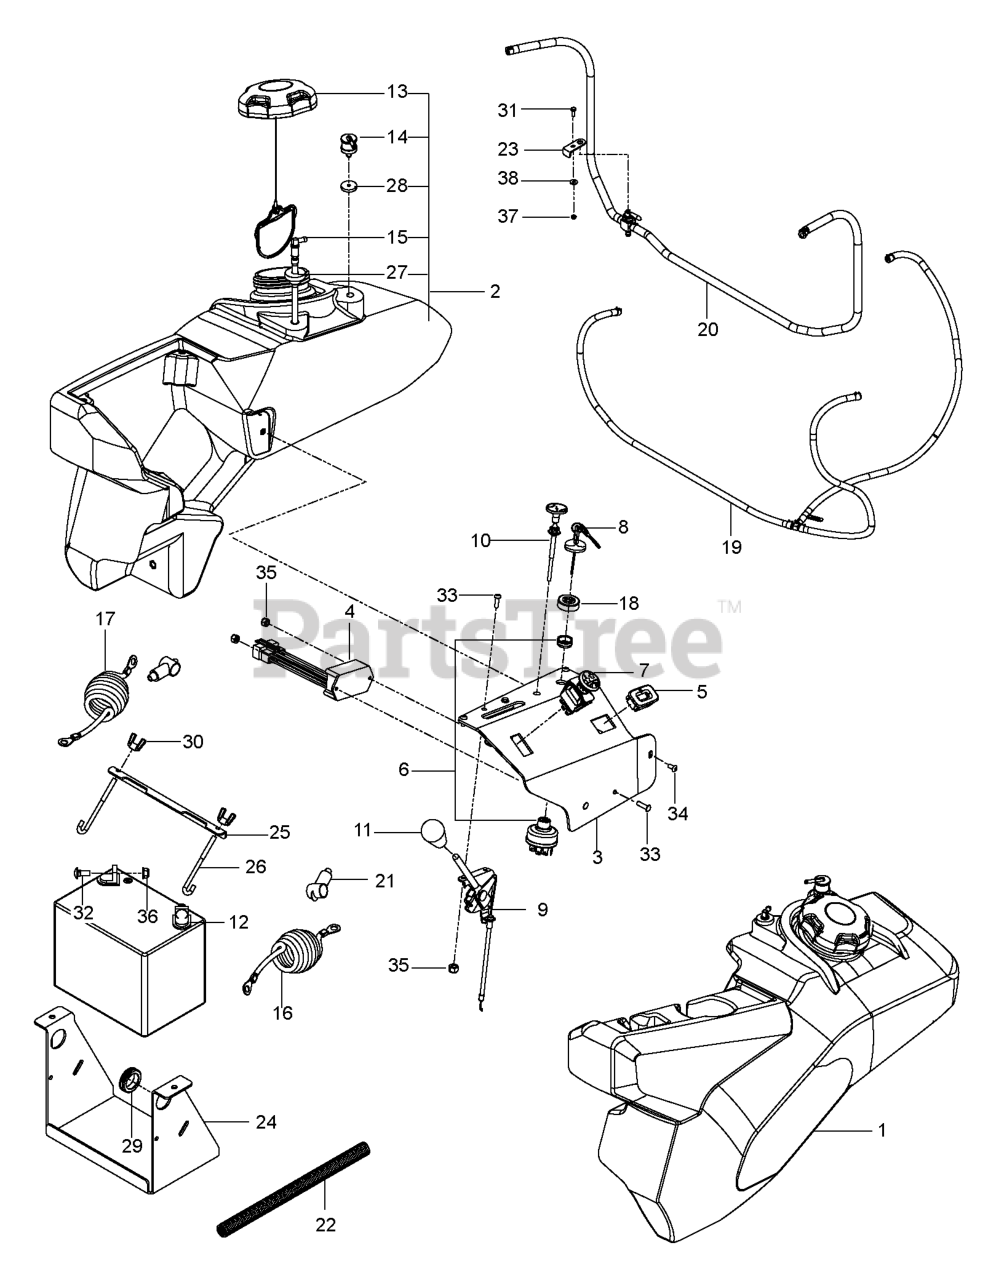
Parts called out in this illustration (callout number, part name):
1	FUEL.TANK.ASM.LH.PZ.GRY.17
2	FUEL.TANK.ASM.RH.PZ.GRY.17
3	PANEL.CONTROL.GAS.GRAY
4	TIMER, SEAT
5	GUAGE.SRVCMNDR.HRMTR.
6	SWITCH, IGNITION, INDAK
7	RP SWITCH.PTO.TERMINAL.STD.RED
8	KEY, IGNITION
9	CABLE, THROTTLE, 46"
10	CABLE, CHOKE, 48"
11	KNOB - SHIFT
12	BATTERY, 12 V 330 AMP
13	CAP, FUEL
14	VALVE.FUEL.CHECK
15	FITTING, FUEL
16	CABLE, POSITIVE, 55"
17	CABLE, NEG, 55"
18	CAP IGNITION NUT
19	HOSE.ASM.VAPOR.LINE.21-30-39
20	ASSEMBLY, FUEL LINE
22	LOOM SPLIT 5/8, 32"
23	BRACKET.VALVE.PNT.BLACK.X431
24	BRACKET, BATTERY, BLK
25	BRACKET.BATTERY.MOUNT.PLATED
26	HOOK, "J"
27	RUBBER GROMMET
28	GROMMET, CHECK VALVE
29	RUBBER GROMMET
30	WING NUT 1/4
31	HCS 1/4C X 3/4 HCS
32	RP BOLT 5/16-18 X3/4 ZN/YEL GR
33	SCR #10-24 X .75 SKT HD BLK
34	SCR #10-24 X 3/8 SKT HD BLK OX
35	NUT 10-24 NYLOC
36	5/16-18 NYLOC FLANGE NUT
37	JAM NUT 1/4C (2 2 PW01)
38	WASHER 1/4 FLAT
